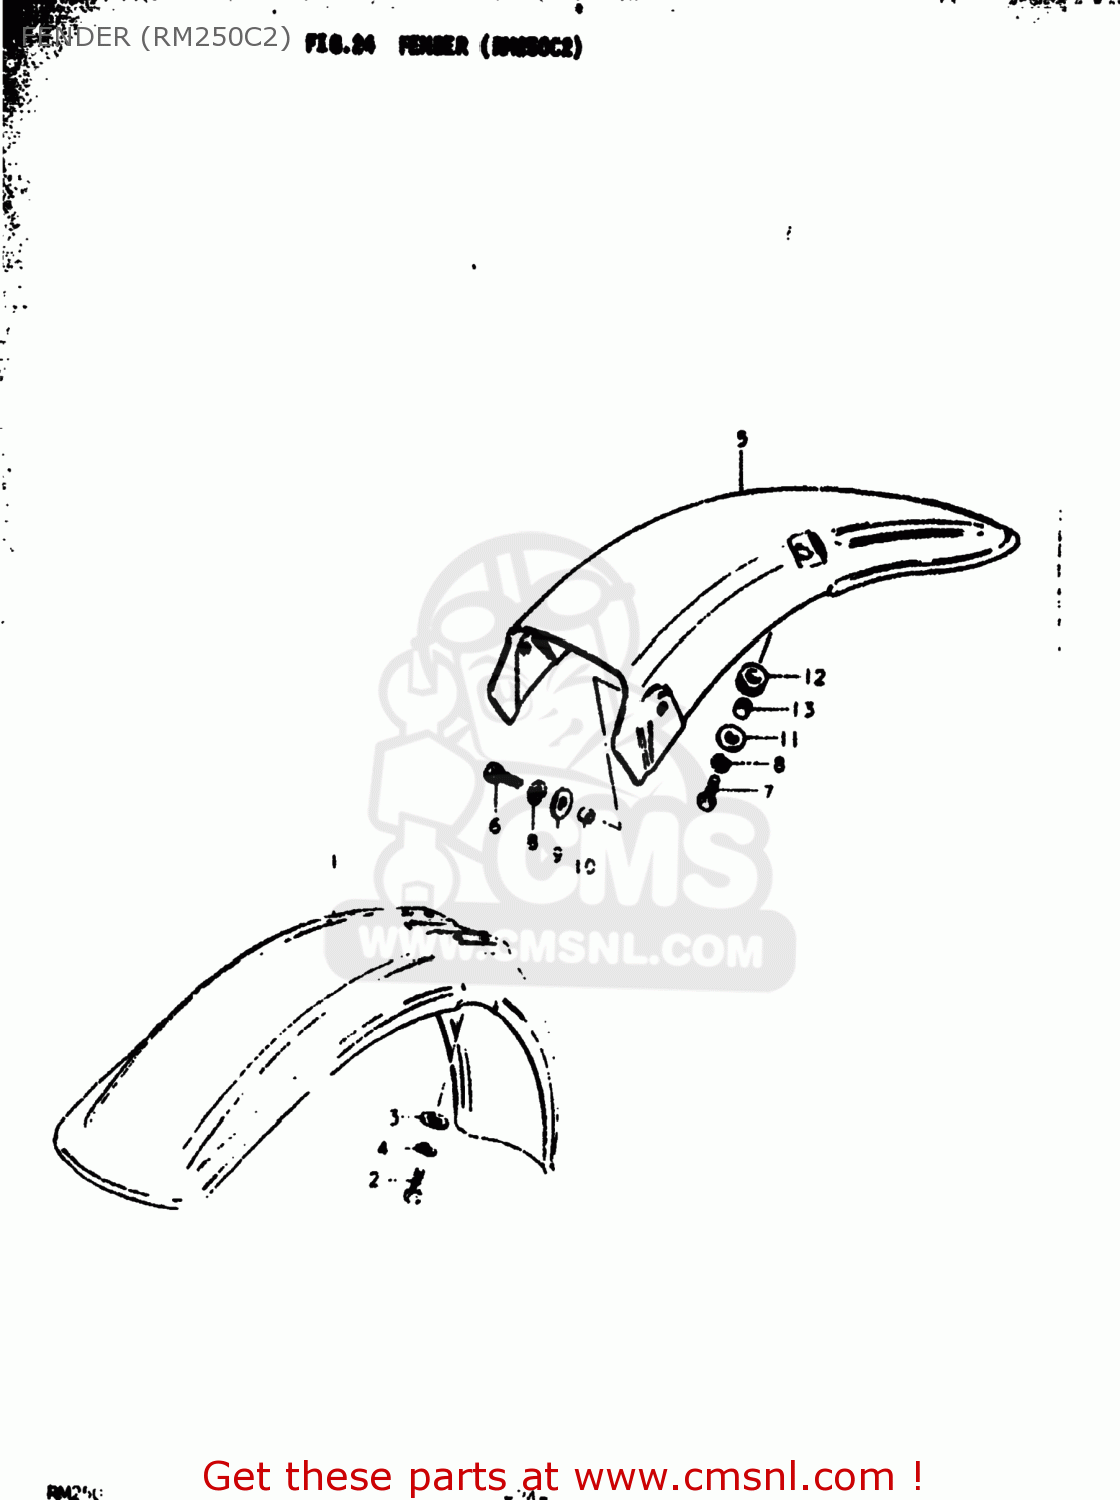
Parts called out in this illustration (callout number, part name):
1	FENDER,FRONT
2	BOLT
3	WASHER
4	LOCK WASHER
5	FENDER,REAR
6	BOLT, UPPER
7	BOLT
8	WASHER,LOCK
9	WASHER
10	SPACER (6.1X8X5.2)
11	WASHER (6.5X24X1.6)
12	CUSHION
13	SPACER(6.5X9X26)
